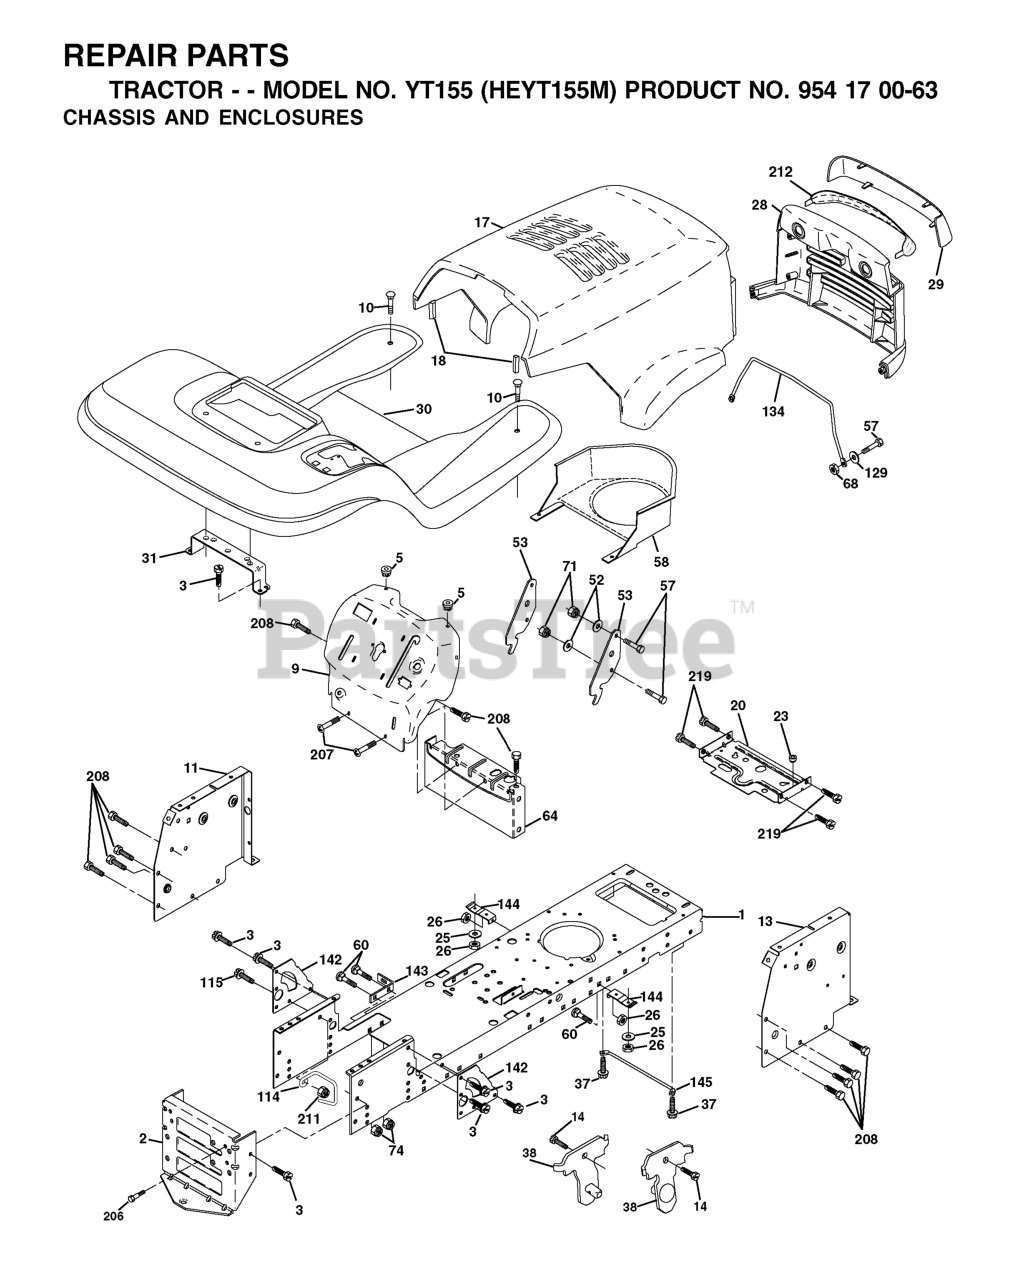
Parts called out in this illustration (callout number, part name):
1	CHASSIS STAMPING
2	DRAWBAR, 12GA
3	SCREW 3/8-16X3/4
5	BUMPER.RUBBER.HOOD
9	DASH
10	BOLT D
11	PANEL.DASH.LH.LTX
13	PANEL ASM, DASH RH
17	HOOD
18	BUMPER HOOD T
20	PLATE MTG.BATTERY/FUEL TANK
23	BUSHING.SNAP.NYL.BLK.
25	WASHER
26	NUT
28	GRILL
29	LENS
30	FENDER FOOTREST
31	BRACKET.SUPPORT.FENDER
37	Screw 5/16-18 x 1/2 Hex, Self Tapping 5/16-18 x 1/2
38	BRACKET.ASM.PIVOT.MOWER.REAR
53	BRACKET PNT PICK OFF LT/PL
57	BOLT
58	AIR DUCT P/L/LT
60	Bolt - Rd. Hd. Sq. Neckiage 3/8 16 x 3/4
64	DASH LOWER
68	NUT
71	NUT.CROWNLOCK.1/4
114	BELT GUIDE
115	SCREW.3/8-16
134	ROD SUPPORT HOOD LT/PL HUS.
142	PLATE REINFORCEMENT
143	BRACKET, SWAY BAR
144	BRKT, FOOT REST
145	ROD PIVOT CHASSIS/HOOD
206	SHOULDER BOLT 5/16-18TT
207	SCREW, 5/16-18 X 1/2
208	SCREW 3/8-16X1/2
211	NUT
212	INSERT LENS REFLECTOR
219	SCREW
